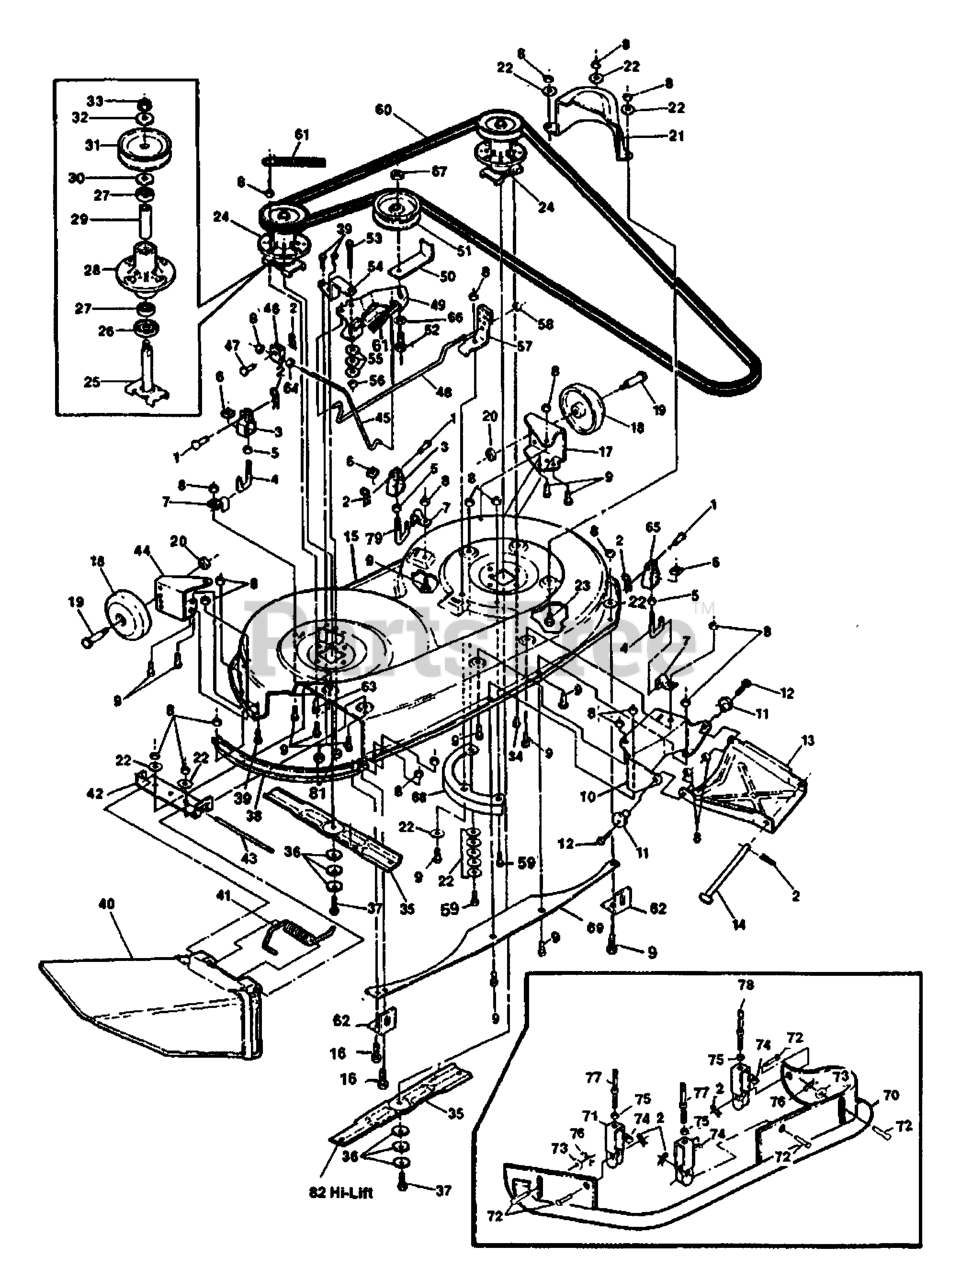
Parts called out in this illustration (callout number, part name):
3	HOLDER
5	NUT
6	NUT
7	CLAMP
8	NUT
9	SCREW
10	BRACKET, FRONT
13	BRACKET
15	COVER
16	SCREW
17	HOLDER, L.H.
18	WHEEL
20	NUT
22	WASHER
23	SCREW
24	BRACKET
25	HOLDER
26	SEALING RING
27	BALL BEARING
28	HOUSING
29	SPACER
31	PULLEY
33	NUT
34	SCREW
37	SCREW 3/8 - 16X1
38	REPL BY 533 31 70-39
39	SCREW
40	PROTECTOR
41	SPRING
42	REPL BY 533 31 70-17
44	HOLDER, R.H.
51	PULLEY
52	SCREW
55	WASHER
56	NUT
58	NUT
59	SCREW
60	BELT
61	SPRING
63	SCREW
64	NUT
65	HOLDER
66	WASHER 3/8ä
67	NUT
68	BAFFLE, DECK NLA
69	BAFFLE NLA
73	WASHER
75	NUT
82	CUTTING BLADE
